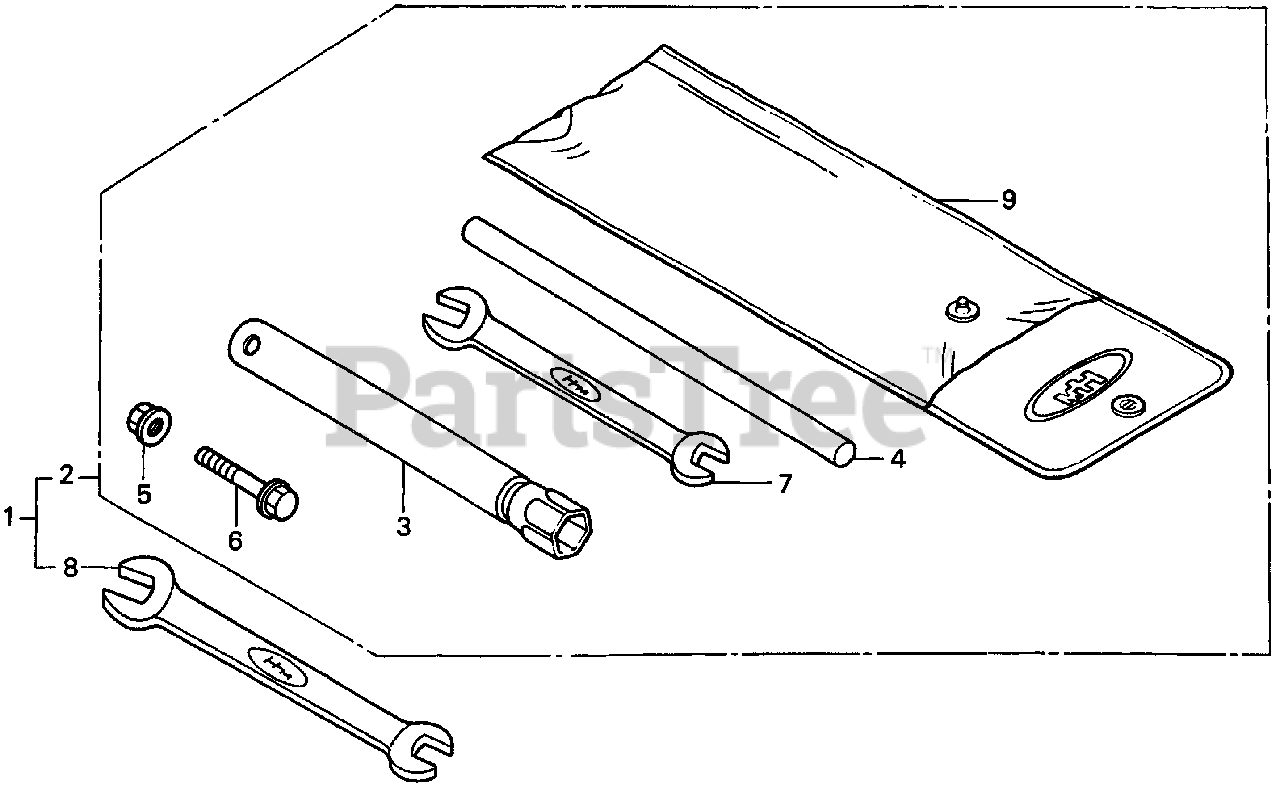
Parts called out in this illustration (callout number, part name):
3	WRENCH, SPARK PLUG (NOT AVAILABLE)
4	HANDLE, BOX WRENCH (NOT AVAILABLE)
5	NUT, SELF-LOCK (6MM)
6	BOLT, FLANGE (6X35)
7	WRENCH (10X12) (OPEN END)
8	WRENCH (10X14) (OPEN END)
